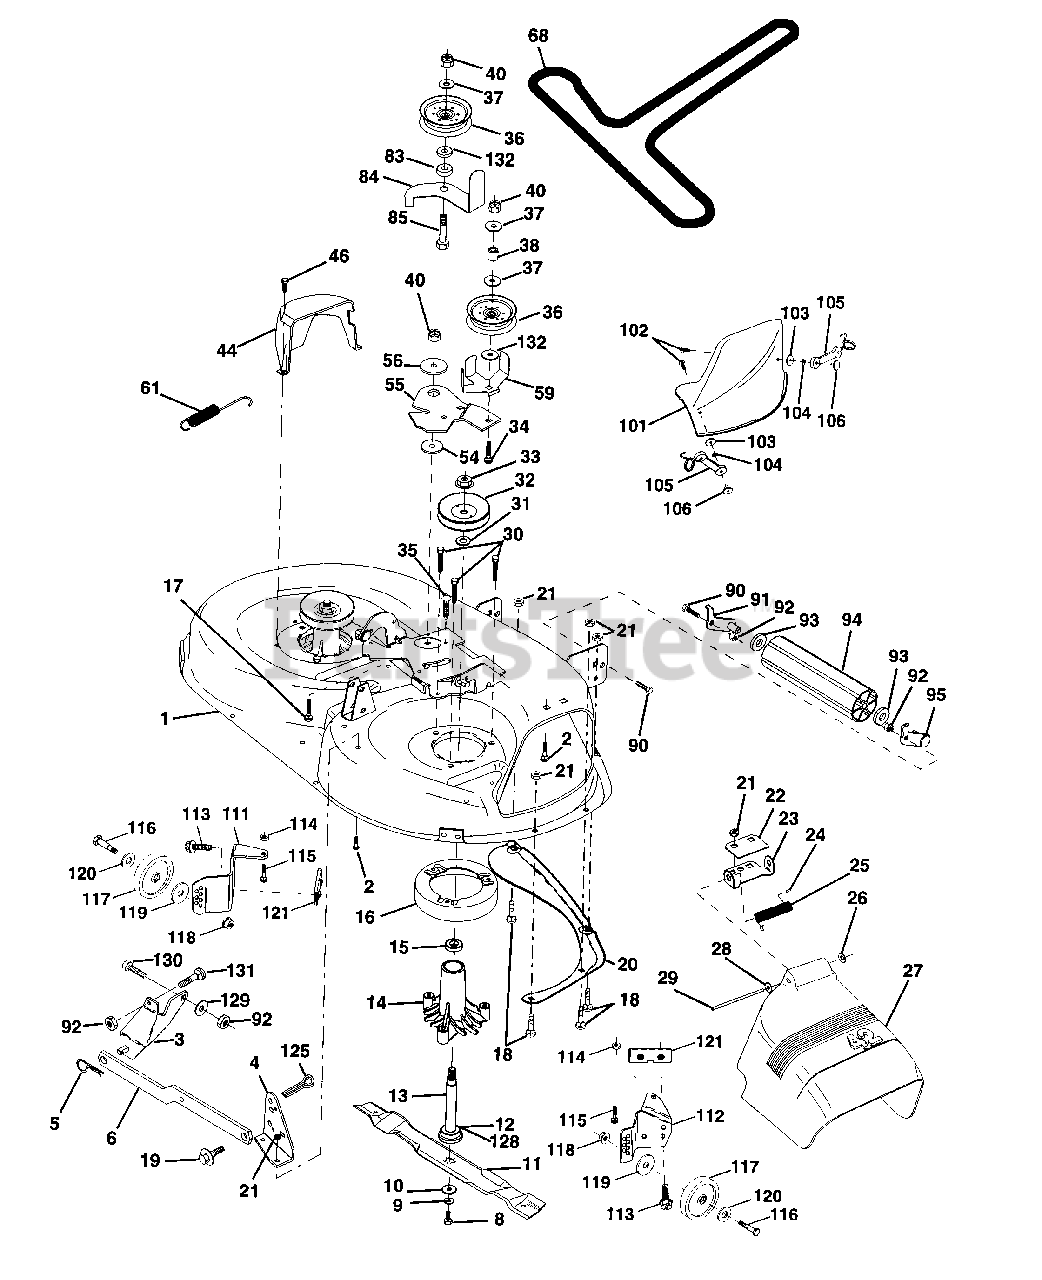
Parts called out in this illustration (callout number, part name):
1	Housing Asm Mower 42" 94 T-Path
2	Bolt Rdhd Sqnk 5/16-18unc X 3/4
3	Bracket Asm Fr Sway Bar 38/42
4	Bracket Asm Deck 42" sway Bar
5	Retainer Spring
6	Arm Suspension Rear
8	Bolt 3/8-24 x 1 25 Gr8 Patched
9	Washer Lock Hvy 3/8 Unplated
10	Washer Hard Blade Mower Vented
11	Blade Mower Mulching 42"
12	Bearing Ball #6204 (Mandrel)
13	Shaft Asm W/lower Bearing
14	Housing Mandrel Vented(machd)
15	Bearing Ball Mandrel
16	Stripper Round Mower
17	Bolt Rdhd Sqnk 3/8-16 X 2-1/4
18	Bolt Carr 5/16-18 X 5/8
19	Bolt Shoulder
20	Baffle Vortex 42
21	Nut Crown Lock 5/16-18
22	Stiffener Bracket 42" deck
23	Bracket Deflector Mower 42"
24	Cap Sleeve 80 x 112 Blk Mower
25	Spring Torsion Deflector 2 52
26	Nut Push Phos & Oil
27	Shield Deflector Mower 42" Blk
28	Washer 11/32 X 5/8 X 16 Ga
29	Rod Hinge 42" 6 75 Wlg
30	Screw Thdrol Hex Hd Zinc Mwr.
31	Washer Spacer Mower Vented
32	Pulley Mandrel 42"
33	Nut 9/16 top Lock Flng Cntr
34	Bolt ROHD 3/8-16 UNC x 2-3/4 Gr5
35	Fastner Christmas Tree
36	Pulley Idler Flat 3 060
37	Washer 13132 X 13/16 X 16 Ga
38	Spacer Spring Stop Idler
40	Nut Lock 3/8-16 Unc
44	Guard Mandrel LH Black
46	Screw Thdrol 1/4-20 x 5/8
54	Washer Hardened
55	Arm Idler 42" mower LT/YT
56	Spacer Retainer Pm Mower
59	Guard, Belt
61	Spring Ext. Elect
68	V-Belt Mower
83	Washer Sintered
84	Keeper Belt Idler
85	Bolt Carriage 3/8-16 x 2-1/4 Gr.5
90	Bolt Fin Hex 3/8-16unc X 1
91	Bracket Asm Noseroller LH
92	Nut Lock Hex w/ins. 3/8-16 UNC
93	Washer 17/32 X 7/8 X 16 Ga
94	Roller Nose 38 & 42
95	Bracket Asm Noseroller RH
101	Cover Mulching 42" Blk
102	Screw
103	Washer #10
104	Washer Lock #10
105	Latch Asm Bagger
106	Nut Weld .327/.304 #10-24
111	Bracket Wheel Gauge Lh 42" Deck
112	Bracket Gauge Wheel Rh 42" Deck
113	Screw Thdrol 5/16-18 x 3/4 TYT
114	Nut Keps 5/16 - 18 UNC
115	Bolt Carriage 5/16 - Unc x 1/2
116	Bolt Shld "A" 2.41 "8" 1.66
117	Wheel Gauge blk. 4.93
118	Nut Centerlock 3/8-16 UNC
119	Washer 3/8 x 7/8 x 14 Ga.
120	Washer 17/32 x 15/16 x 12 Ga.
125	Cotter Pin
128	Washer Felt
129	Washer 13/32 x 13/16 x 12 Ga.
130	Bolt Fin Hex 3/8-16 UNC x 1 Gr. 5
131	Bolt RDHD SQNK 3/8-16 UNC x 1
